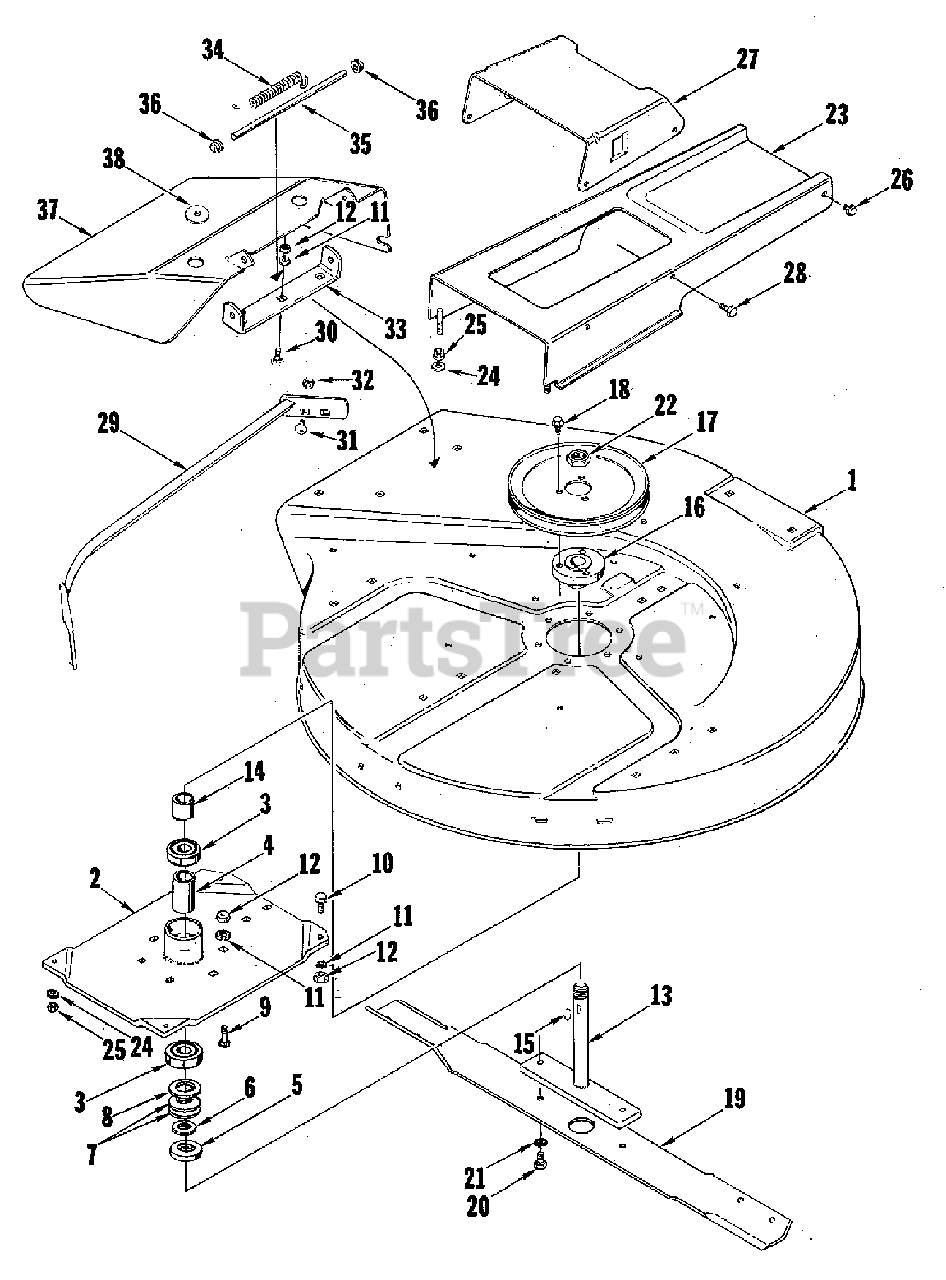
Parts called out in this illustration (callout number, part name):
1	HOUSING, Mower 30"
2	ARBOR TUBE ASSEMBLY
3	BEARING, Ball
9	BOLT, Carriage, 5/16-18 x 1
10	SCREW, Hex, 5/16-18 x 1
11	WASHER, Lock, 5/16
12	NUT, Hex, Full, 5/16-18
13	ARBOR ASSEMBLY
18	SCREW, Thread Forming, 3/8-16 x 3/4
21	WASHER, Lock, 3/8
22	NUT, Hex Jam, 3/4-16
23	LOWER COVER ASSEMBLY
24	WASHER, Plain, 5/16
25	NUT, Flange, 5/16
26	SCREW, Hex, 3/8-16 x 1/2
27	COVER, Upper
28	SCREW, 1/4-20 x 3/8
29	STONE GUARD ASSEMBLY
30	BOLT, Carriage, 5/16-18 x 3/4
31	BOLT, Carriage, 5/16-18 x 1/2
32	NUT, Hex Full Lock, 5/16-18
38	WASHER, Special
